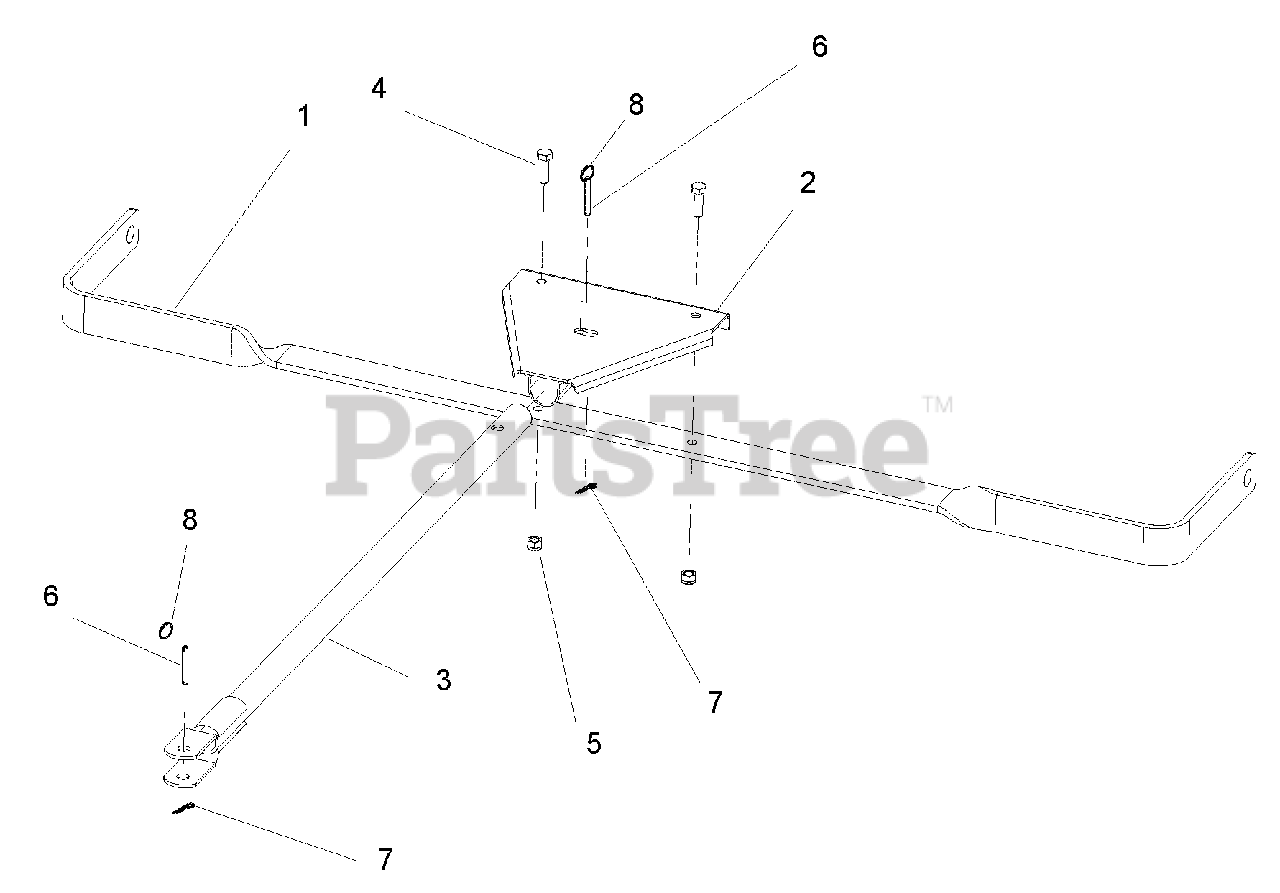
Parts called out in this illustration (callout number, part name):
2	Hitch Plate
3	Tongue Weldment
4	Bolt, .31-18 x 1.00 Hex 5
5	Nut, .312-18 Nyloc
6	Pin, Hitch
7	Pin, Hair .091 x 1.63
8	Ring, Retaining
